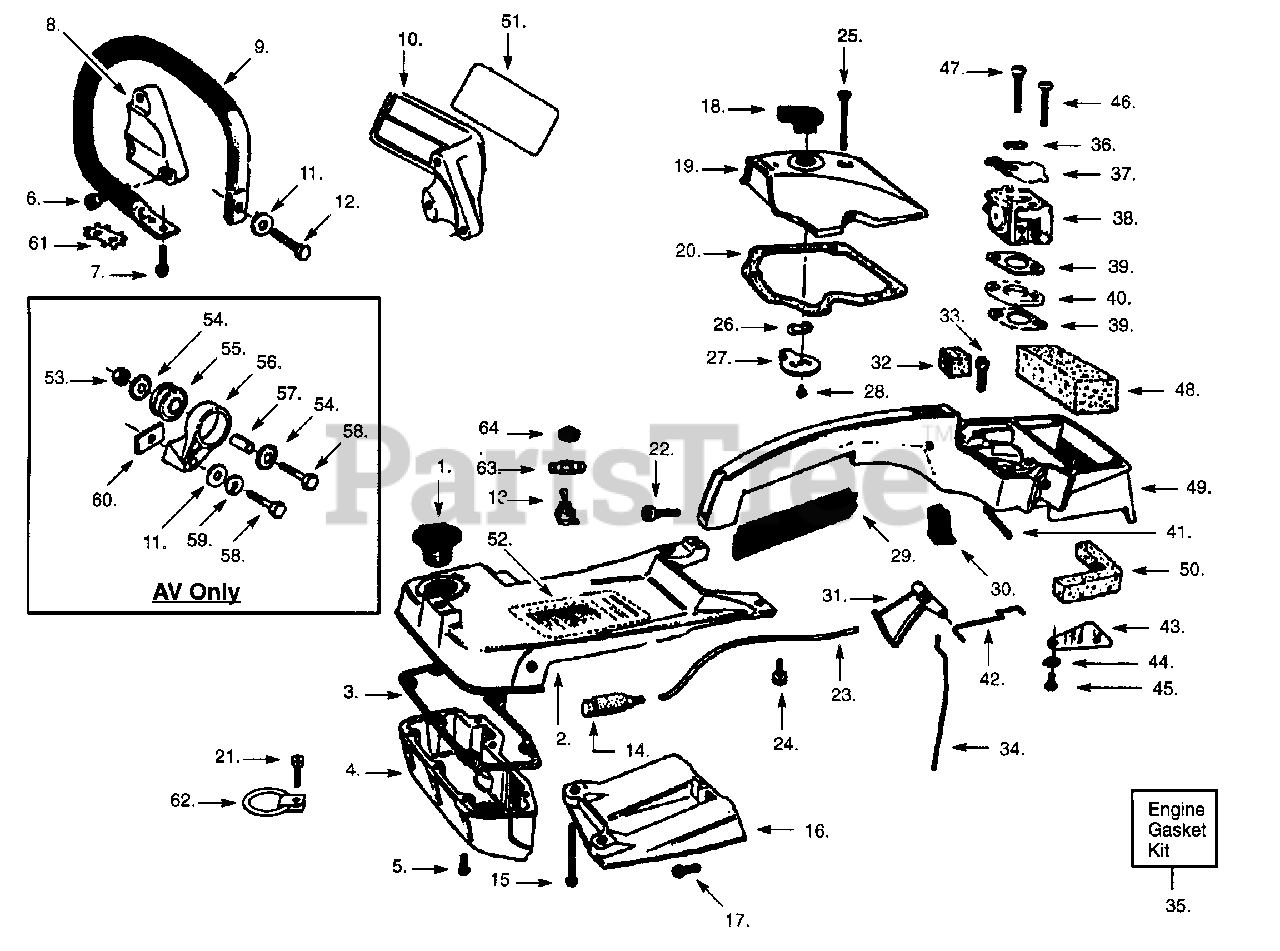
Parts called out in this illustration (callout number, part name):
1	Fuel Cap Ass'y.
2	Fuel Tank Top
3	Fuel Tank Gasket
4	Fuel Tank Bottom
8	Handguard Cap
10	Handguard
13	Start/Stop Switch
14	Fuel Pick-up Ass'y.
16	Cylinder Shield
18	Choke Knob
19	Carburetor Cover
20	Carb. Cover Gasket
23	Line Kit (Bulk 8133)
26	Wave Washer
27	Choke Lever
29	Handle Grip
30	Oil Pump Button
32	Throttle Wire Boot
34	Oil Pump Push Rod
35	Engine Gasket Kit (Inc. 3,20,32,39,50,55)
36	Wave Washer
37	Choke Shutter
38	Carburetor
39	Carb. Gasket
41	Trigger Pin
42	Throttle Rod
48	Air Filter
49	Handle & Carb. Hsg.
50	Dust Seal
51	Handguard Decal
52	Instruction Decal
54	Cup Washer
55	Isolator
56	Isolator Mtg. Bracket
59	Lockwasher
61	Retainer
62	Rope Ring Ass'y.
